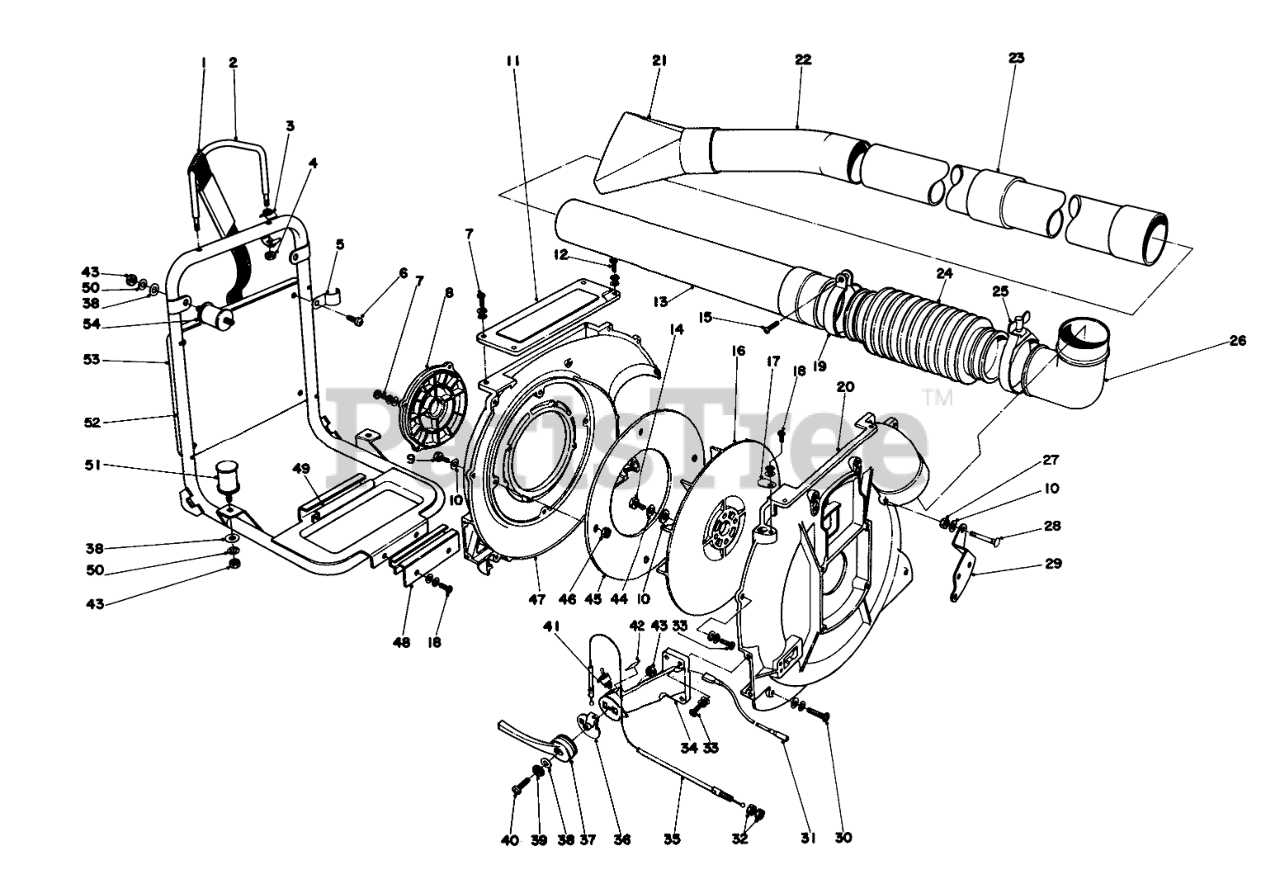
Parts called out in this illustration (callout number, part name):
1	Shoulder Strap
3	Adapter
4	Locknut
5	Bracket Cushion
6	SCREW-SHWH
7	Screw
8	Grid, Fan Case
10	WASHER
11	Plate
12	Screw
13	STRAIGHT PIPE/SWIVEL
15	Screw
18	SCREW
19	Clamp
20	Fan Case, Starter Side
21	FAN HD NOZZLE
22	CURVED PIPE
23	Straight Pipe
24	FLEXIBLE PIPE
25	CLAMP
26	Elbow
27	Capnut
28	Bolt, Elbow
29	Bracket, Muffler Cover
31	Lead, Switch
33	Screw
34	THROTTLE LEVER BRKT
35	THROTTLE CABLE
37	Throttle Lever
38	Washer
39	Washer
40	Screw
41	SWITCH
42	STOP SWITCH DECAL
44	Washer
45	Separator
47	Fan Case
48	Bracket-Fuel Tank
49	Cushion-Fuel Tank
50	Washer
51	Cushion
52	Frame, Back Pack
53	Back Pack Pad
54	Cushion
